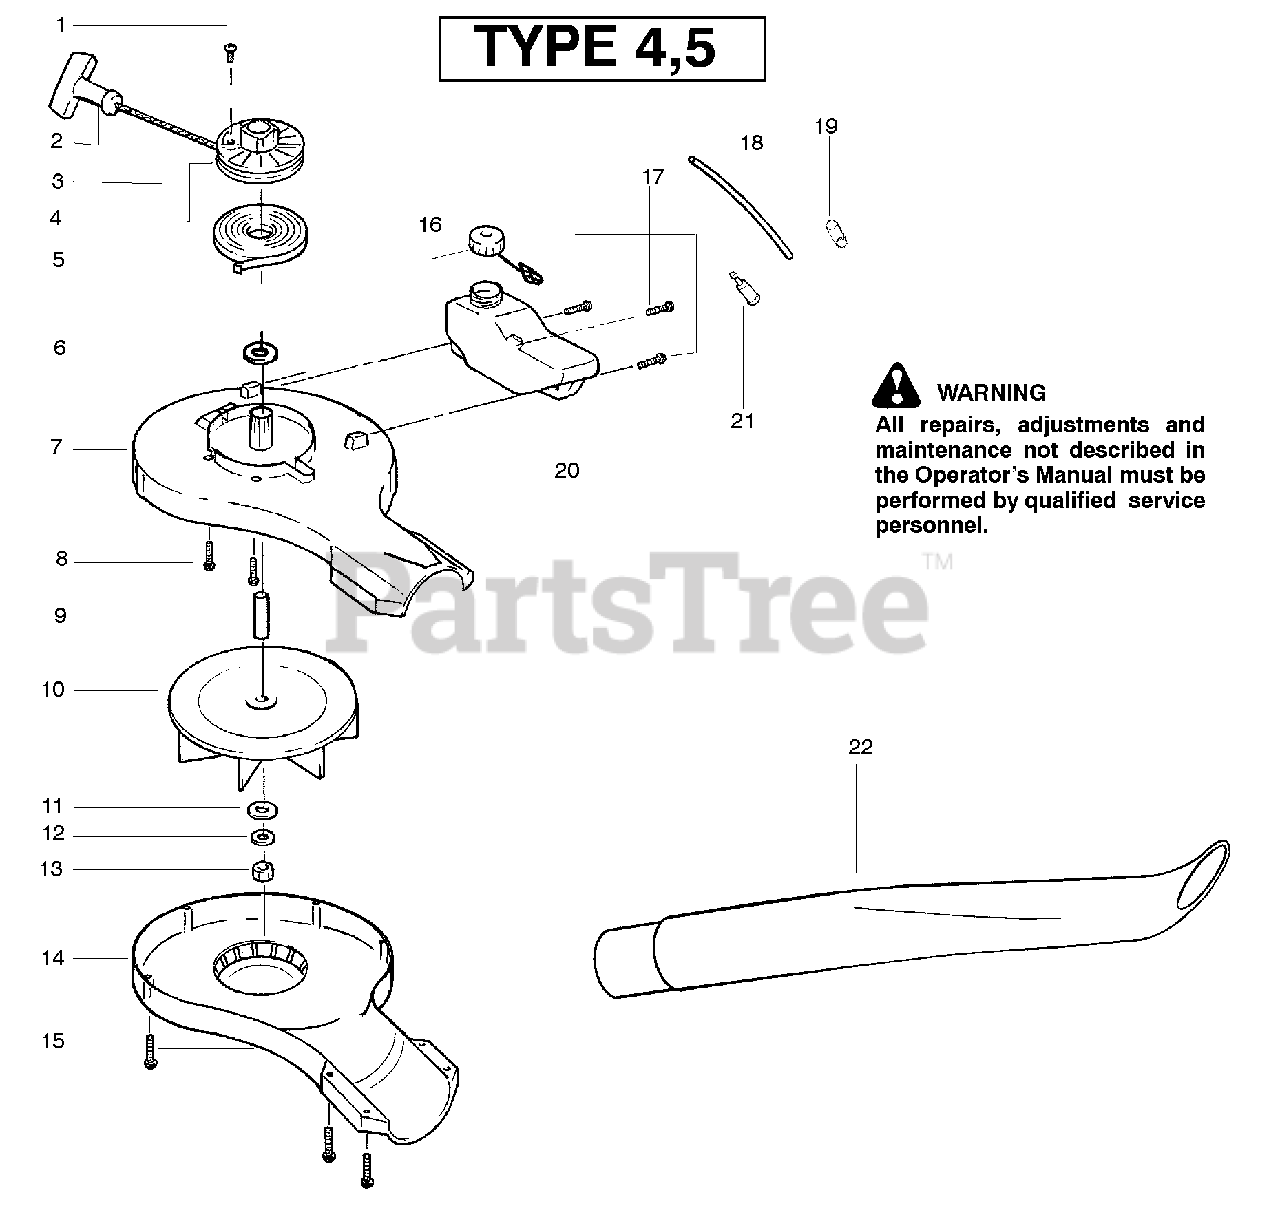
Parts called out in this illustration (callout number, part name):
2	Handle-Starter
3	Kit-Rope
4	Kit-Starter Pulley
5	Spring-Starter
7	Housing-Impeller (Upper)
9	Spacer-Flywheel
10	Assy-Impeller
11	Washer-Flat
12	Lockwasher
14	Assy-Impeller Housing (Lower)
16	Assy-Fuel Cap
18	Kit-Fuel Line
19	Grommet-Fuel Line
20	Assy-Fuel Tank
21	Fuel Pick-up Ass'y.
22	Tube-Blower
